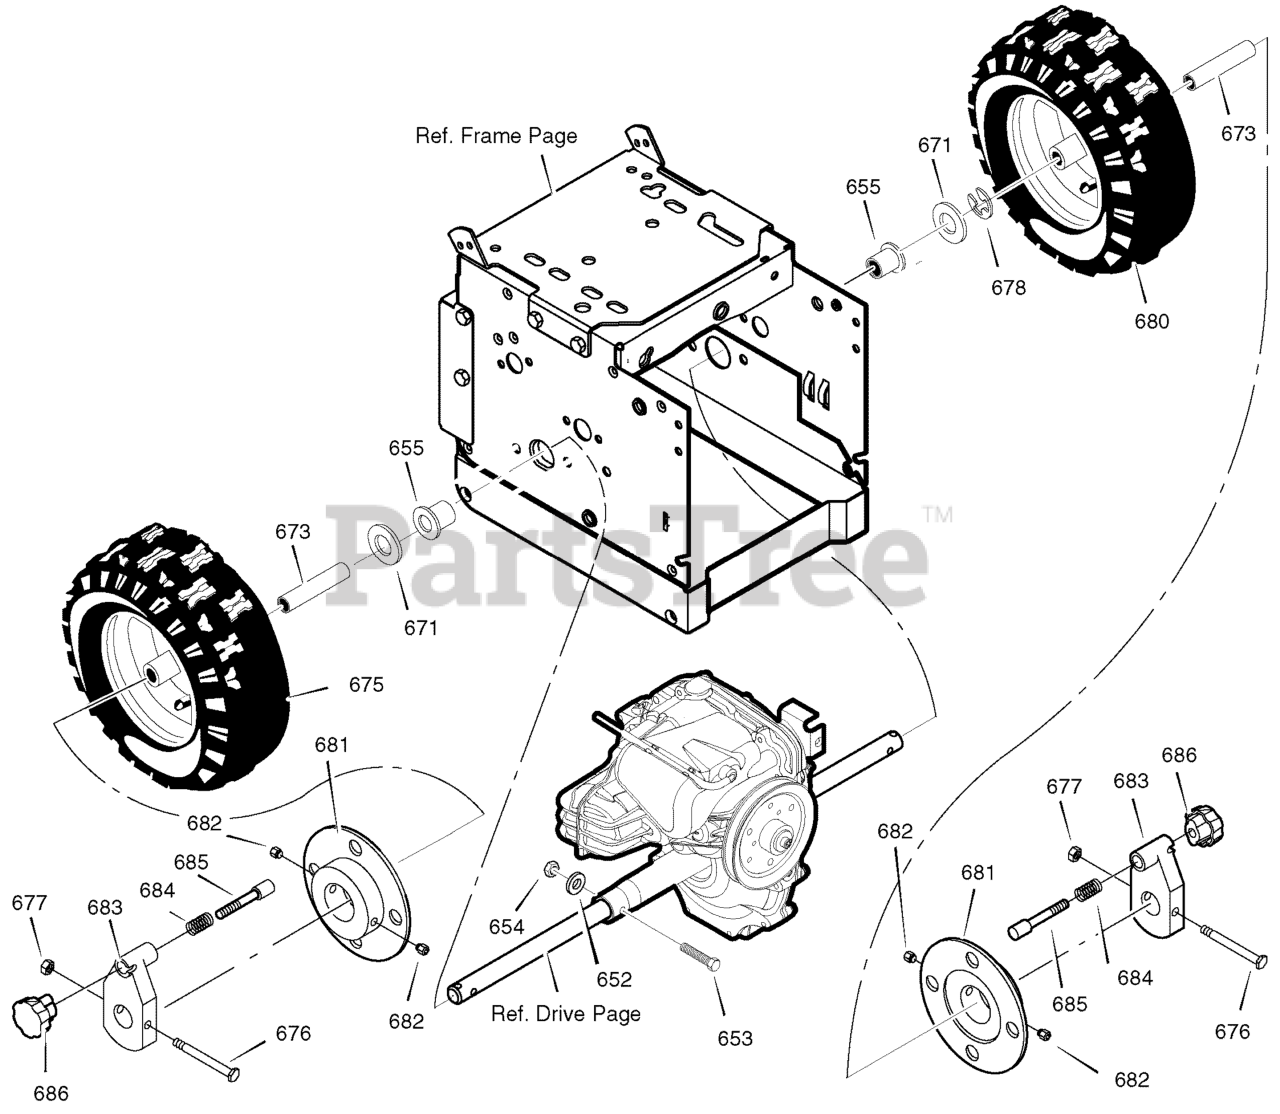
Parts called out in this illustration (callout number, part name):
652	SPACER
653	SCREW,1/4-20 X 1.75
654	NUT, 1/4-20
655	BEARING, AXLE
671	FLATWASHER
673	BUSHING, WHEEL
675	TIRE & RIM, RIGHT
676	SCREW, 1/4-20 X 2.25
677	NUT, 1/4-20
678	RING, RET
680	TIRE & RIM, LEFT
681	DISC, WHEEL
683	HUB, WHEEL LOCK
684	SPRING *
685	PIN, LOCK*
